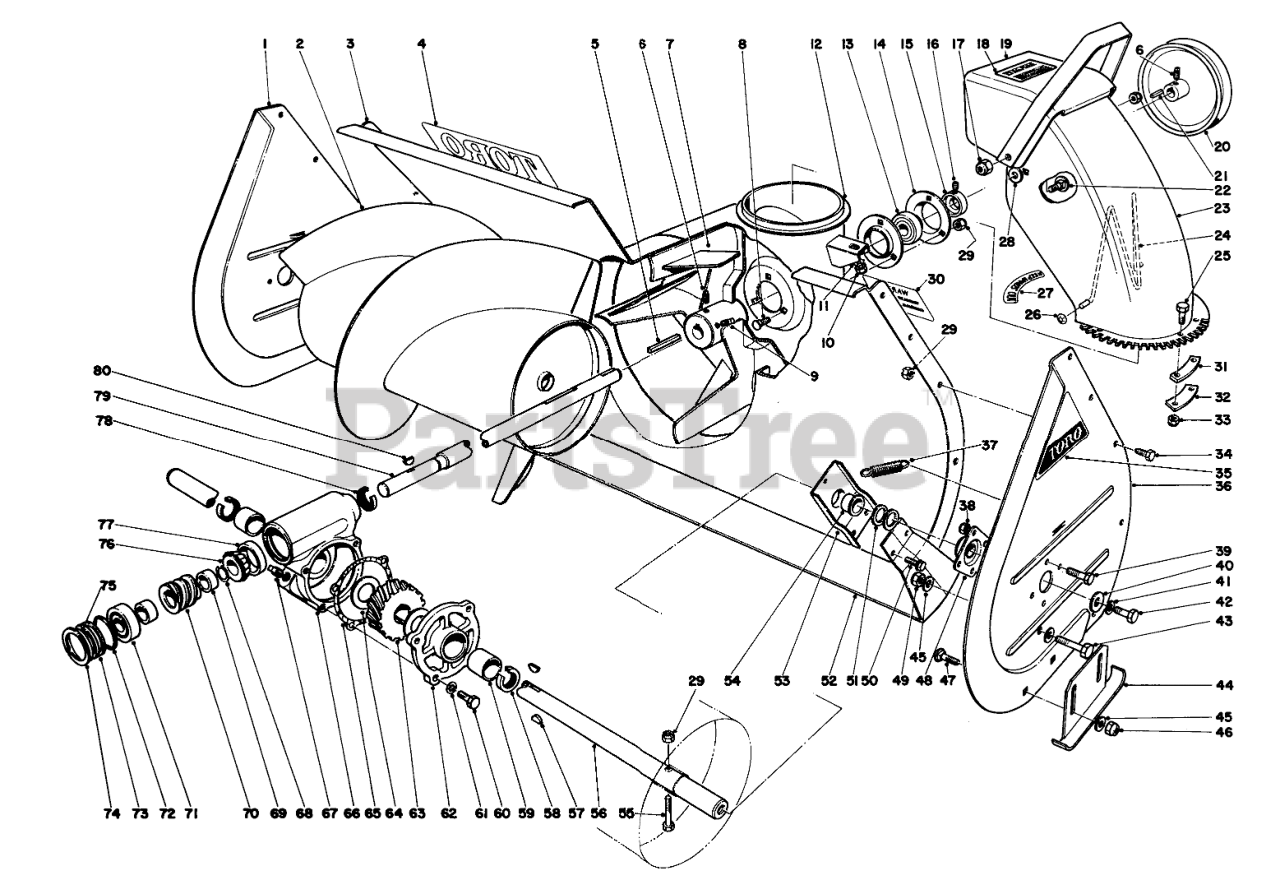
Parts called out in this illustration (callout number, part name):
1	Side Plate
2	Auger
3	Auger Housing (Incl. Ref. #30)
4	Decal-Auger Housing
6	SCREW-SET, SQH
7	Impeller
8	BOLT-CARR
9	SCREW-SET, SQH
10	Nut
11	WASHER-LOCK
12	SUPPORT B
13	BALL BRG W/COLLAR
14	BRG FLANGE
15	EXT LOCKING COLLAR
16	SCREW-HSH
17	NUT-LOCK, NI
18	Decal
19	Deflector (Incl. Ref. #18)
20	1/2 X 9.5 DIA PULLEY
21	SQUARE KEY
22	SCREW-CARR
23	Upper Chute (Incl. Ref. #27)
24	WIRE-CHUTE
26	NUT-PUSH
27	Decal
28	WASHER-FLAT
29	NUT-LOCK, CONE
30	Decal
31	CHUTE TAB SPACER
32	UPPER CHUTE TAB
33	Nut
34	SCREW-HH
35	AUGER SIDE PLT DECAL
36	Side Plate L. H.
37	SPRING-TENSION
38	NUT-LOCK
39	SCREW-HH
40	WASHER
41	WASHER-LOCK
42	SCREW-HH
43	SCREW-HH
44	Skid
45	WASHER-FLAT
46	NUT-LOCK, NI
47	BOLT-CARR
48	Bearing Flange
49	NUT-HEX
50	Hex Hd. Screw
51	Spacer
52	Scraper Blade
53	Scraper Blade Mount (Incl. Ref. #54)
54	BUSHING-FLANGE
55	Auger Bolt
56	26 AUGER SHAFT
57	KEY-WOODRUFF
58	SEAL-OIL
59	Bushing
60	SCREW-HH
61	WASHER-LOCK
62	Cover-Gear Box (Incl. Ref. #59)
63	GEAR-WORM, 27T
64	WASHER-THRUST
65	Gasket
66	Gear Box Auger (Incl. Ref. #59 & 77)
67	PLUG-PIPE, SQH
68	RETAINER RING
69	Spacer
71	.750 BALL BEARING
72	O-RING
74	INTRNL RETAINING RING
76	3/4 ROLLER BRG CONE
77	1.750 ROLLER BRG CUP
78	SEAL-OIL
79	Shaft Worm
80	KEY-WOODRUFF
